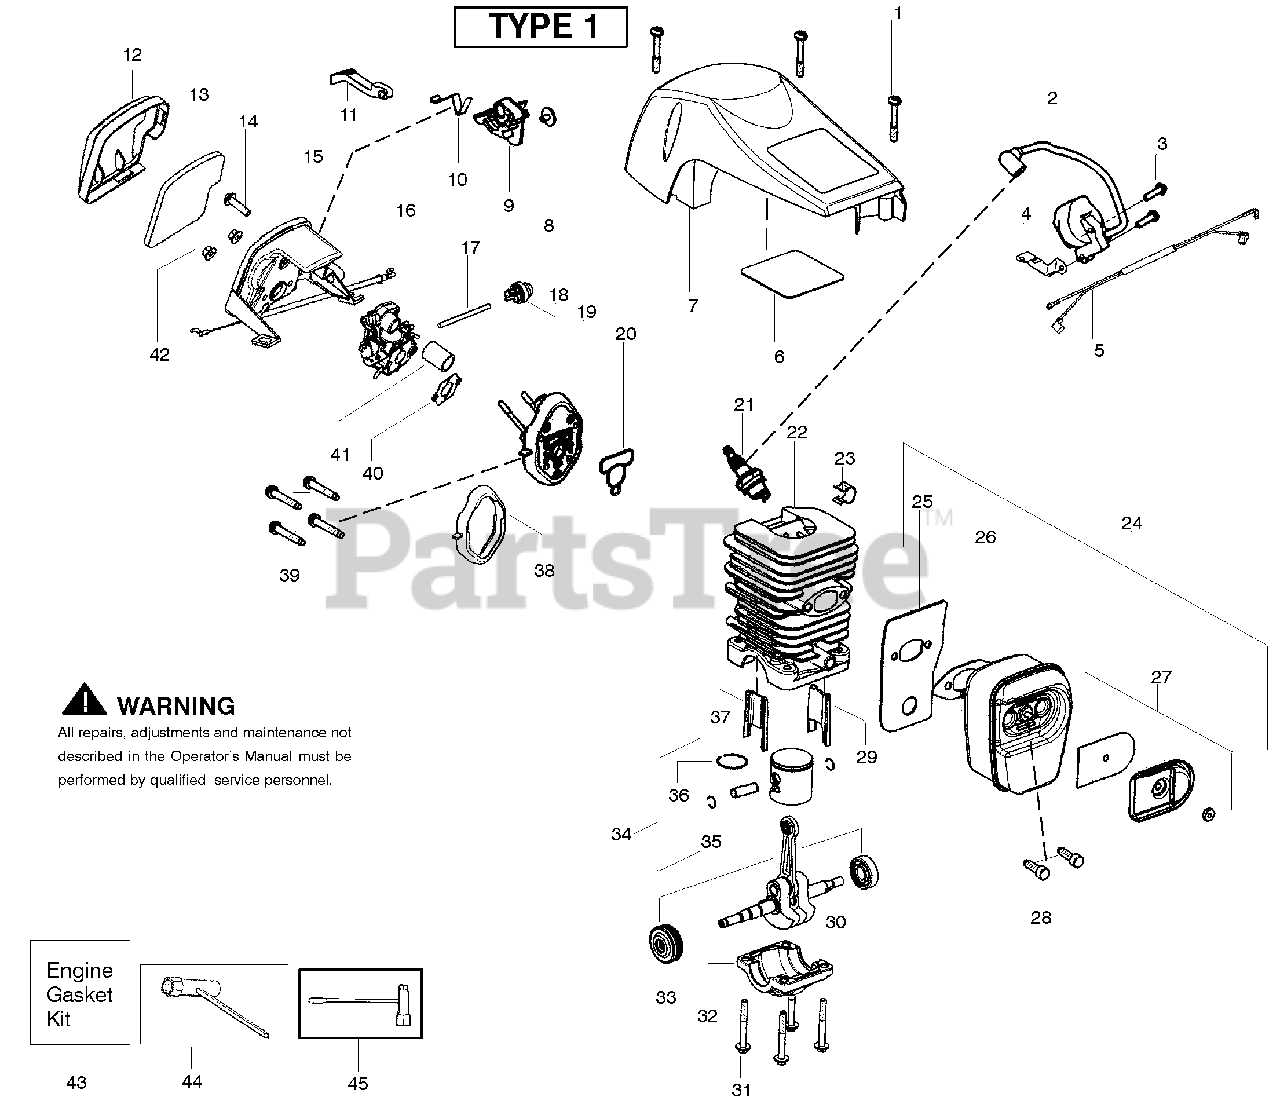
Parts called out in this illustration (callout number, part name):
2	Module-Ignition
4	Strap-Ground
5	Assy-Wire Harness
6	Reflector-Tape
7	Shield-Cylinder
9	Lever-Ignition Switch
10	Spring-Ignition Switch
11	Knob-Choke
12	Cover-Air Filter
13	Filter-Air
15	Housing-Air Filter w/cable
16	Carburetor Zama W26
17	Kit-Fuel Line (Small)
18	Bulb-Purge "snap-in"
19	Kit-Carb. Adaptor
20	Gasket-cyl. o-ring (kit)
21	Accy-Spark Plug (RCJ-7Y)
22	Kit-Cylinder
23	Clip-High Tension Lead
24	Kit-Muffler
25	Backplate-Muffler
26	Gasket-Muffler (kit)
27	Kit-Spark Arrestor
28	Bolt-Muffler
29	Insert-Left (black) Cyl.
30	Assy-Crankshaft/Rod
32	Cap-Crankcase
33	Assy-Bearing/Seal
34	Kit-Piston
35	Retainer-Piston Pin
36	Ring-Piston
37	Insert-Right (gray)Cyl.
38	Seal-Adaptor (kit)
40	Gasket-Carb. (kit)
41	Tube-Intake
42	Nut-Carb.
43	Kit-Gasket
44	Wrench-Bar
45	Scrench
